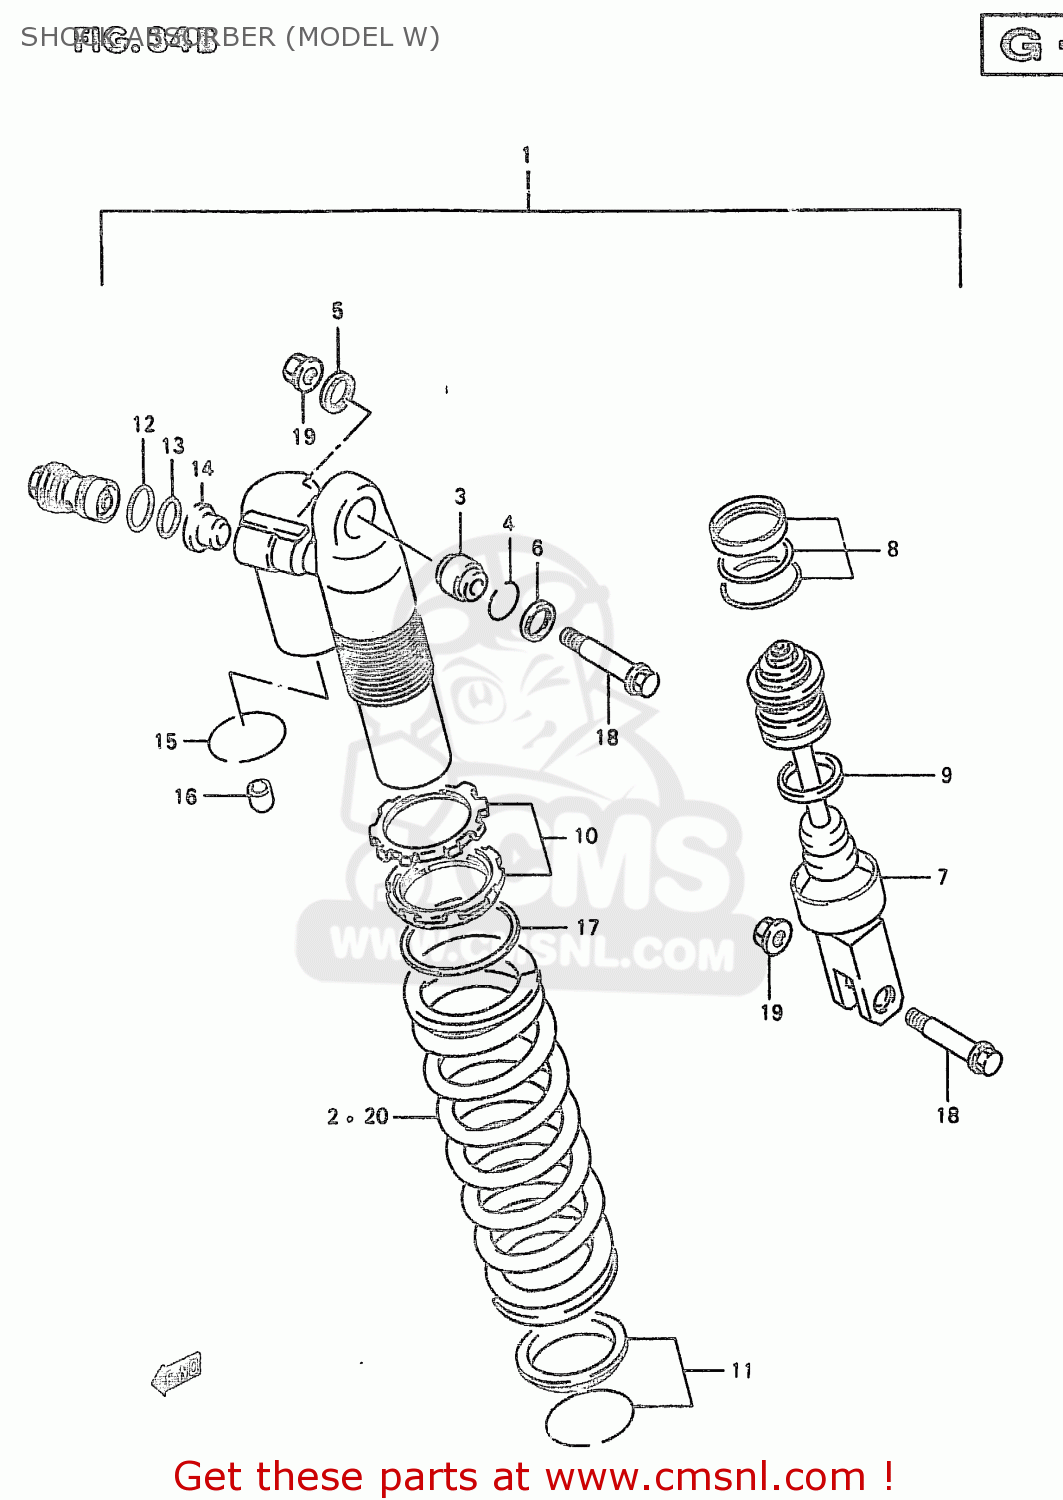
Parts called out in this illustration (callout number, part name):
1	ABSORBER ASSY, REAR SHOCK (BLUE)
2	SPRING,REAR (K=4.9)
3	BEARING,RR SHOCK ABSORBER
4	RING,STOPPER
5	SEAL,DUST UPR,R
6	SEAL,DUST UPR,L
7	ROD,PISTON
8	O RING SET
9	RING,STOPPER
10	ADJUSTER SET
11	SPRING SEAT SET
12	O RING
13	O RING,CTR BOLT UPR
14	COLLAR,ORIFICE
15	RING,STOPPER
16	CAP
17	SEAT,SPRING
18	BOLT(10X47.5)
19	NUT
20	SPRING,REAR (K=4.7)
